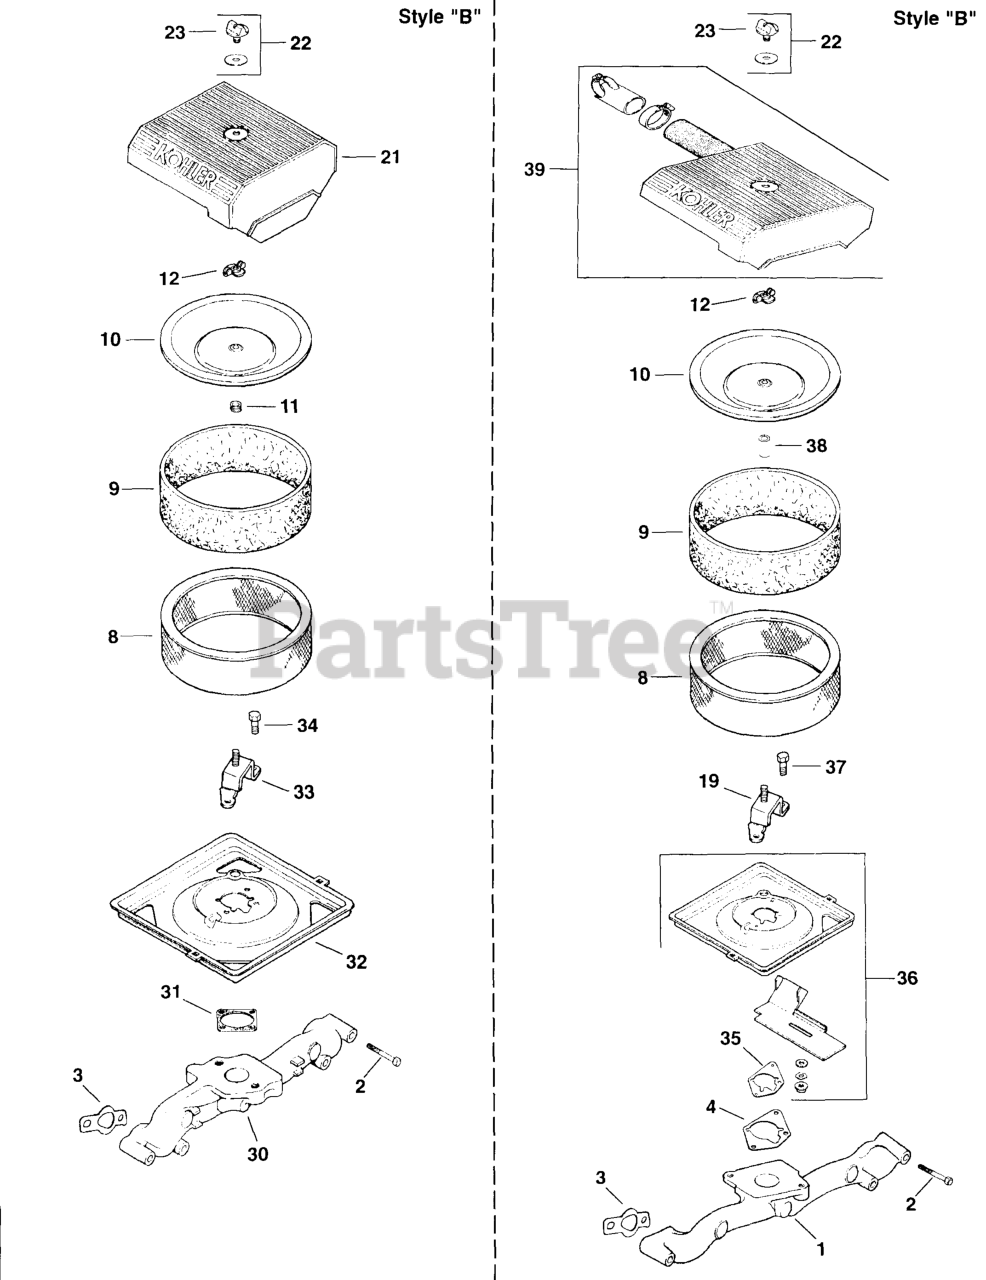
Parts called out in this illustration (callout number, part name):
1	MANIFOLD, METAL INTAKE
2	Screw, hex. flange M6x1.0x55
3	GASKET, INTAKE MANIFOLD USE 24 041 79-S
4	GASKET, AIR CLEANER BASE
8	ELEMENT, AIR CLEANER - Also available Retail Packaged 47 883 03-S1 Air Filter Kit
9	ELEMENT, PRECLEANER (LOW)
10	COVER, INNER AIR CLEANER
11	SEAL, INNER AIR CLEANER
12	NUT, WING
19	BRACKET,AIR CLEANERBASE-USE 24 126 206-S
22	KIT - USE 54 755 01
23	KNOB - USE 25 341 03
38	SEAL, BREATHER
